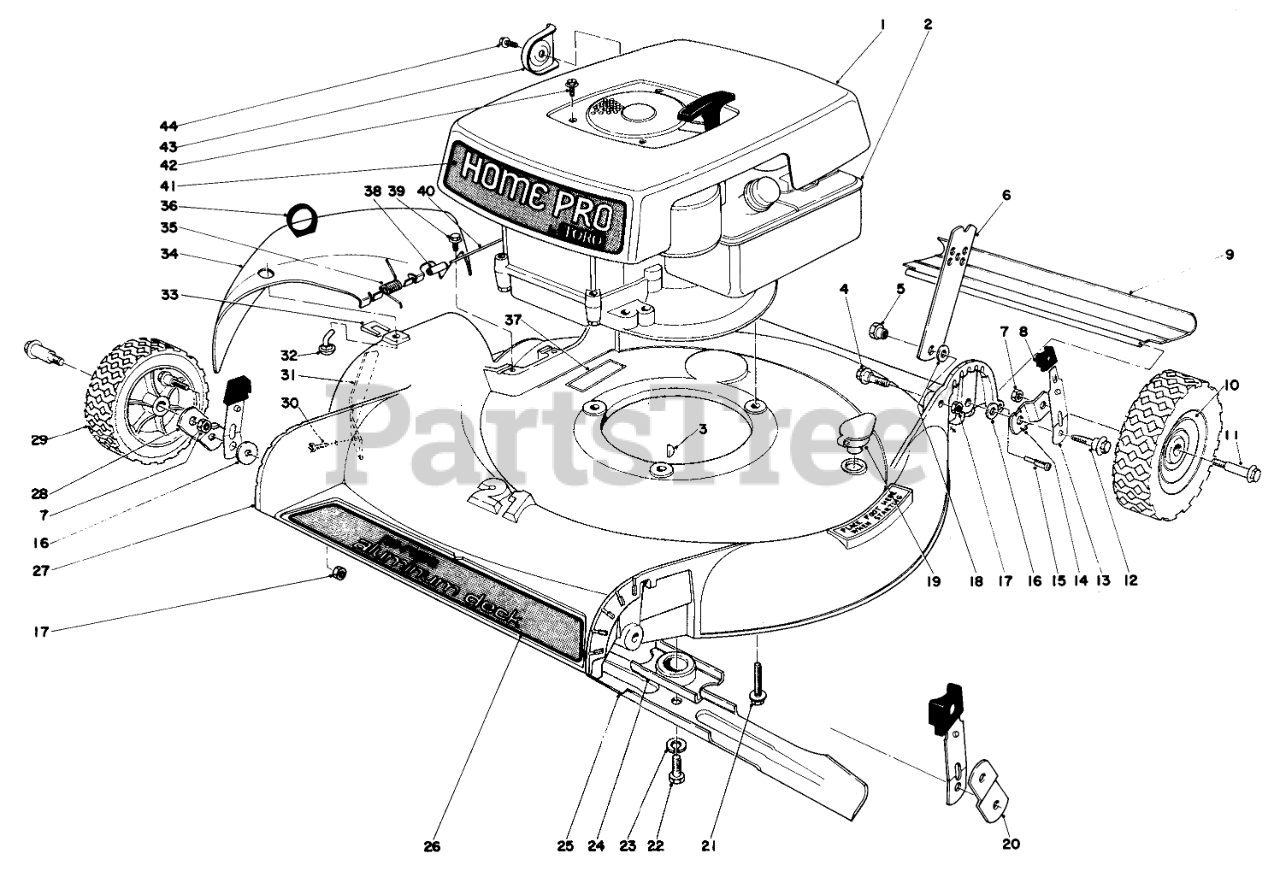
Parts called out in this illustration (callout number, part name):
1	Shroud
2	Engine
3	KEY-WOODRUFF
4	SCREW-SHOULDER
5	HANDLE PIVOT NUT
6	HANDLE LATCH
7	Nut
8	KNOB-ARM
9	SHIELD - TRAILING
10	WHEEL ASM 8
12	PIVOT SCREW
13	SPRING ARM ASM
14	PIVOT ARM PLATED
15	SAFTEY SHIELD SCREW
16	WASHER-PIVOT
17	Nut
18	HANDLE LATCH SPACER
19	WASHOUT PLUG
20	PIVOT ARM C PLTD
21	SCREW-HWHTF
22	SPECIAL SCREW
23	WASHER-LOCK
24	Blade Retailer
25	Blade
26	Decal-Deck
27	Housing
28	PIVOT ARM D PLTD
29	WHEEL ASM 7
30	SCREW THD 1/4 20 5/8
31	Bar Safety
32	BAG CHUTE PIN
33	BAG CHUTE CLIP PIN
34	Deflector
35	TORSION SPRING
36	LIFT LOOP
37	Decal Warning
38	SLEEVE
39	SCREW
40	HINGE PIN
41	Decal Shroud
42	8X1/2 SELF TAP SCREW
43	Deflector
44	Screw
